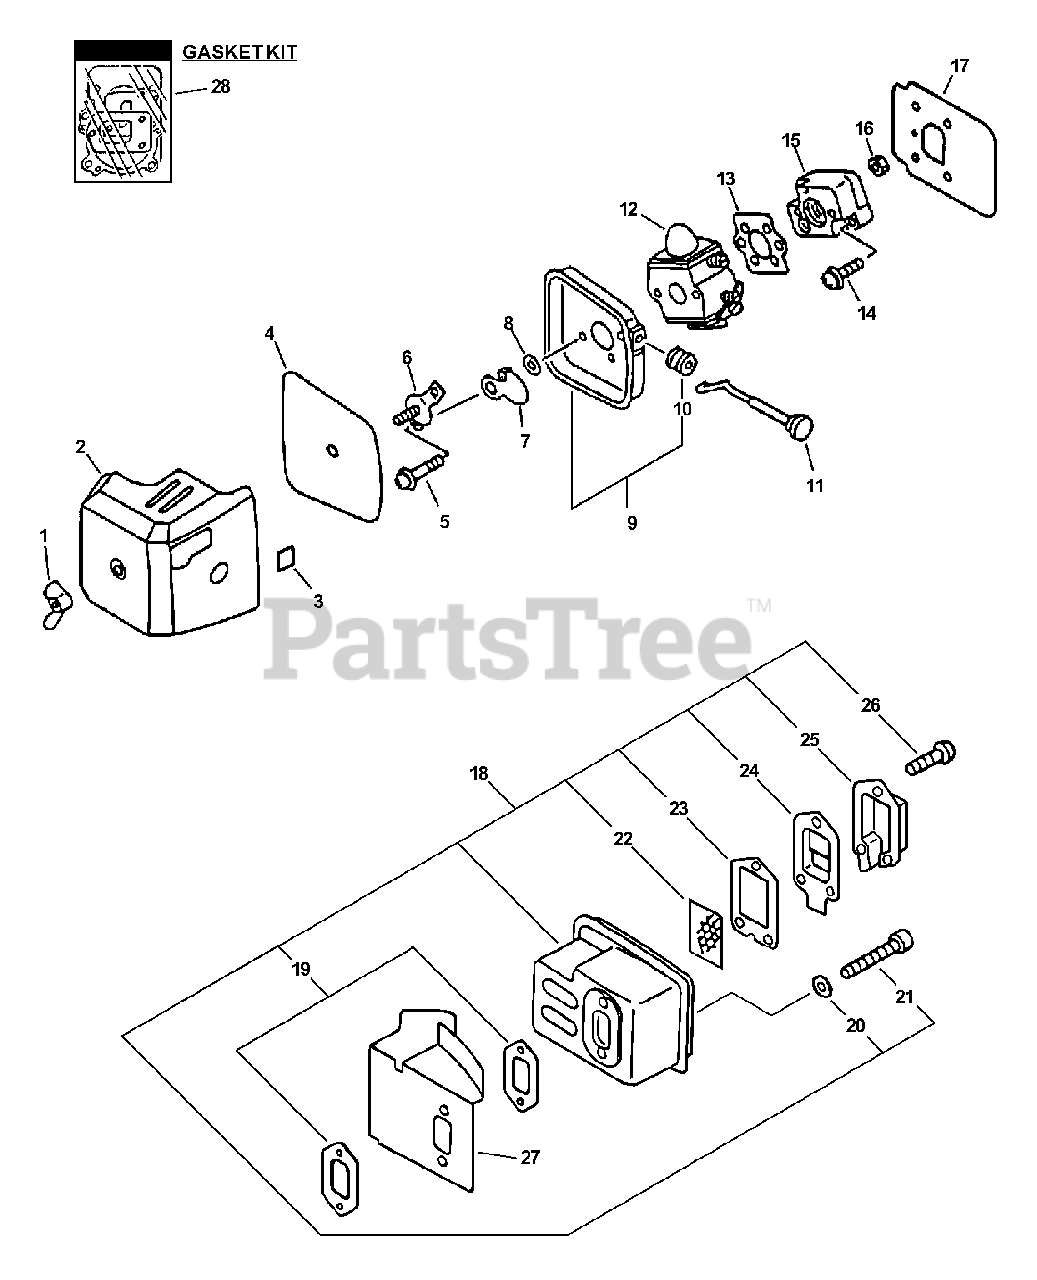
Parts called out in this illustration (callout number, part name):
1	WINGNUT - 6
2	COVER, AIR FILTER
3	LABEL - CHOKE
4	FILTER, AIR
5	SCREW - 5X57
6	PLATE, PREVENT
7	SHUTTER, CHOKE
8	WASHER - 5
9	CASE, AIR FILTER
11	ROD, CHOKE
12	CARBURETOR C1U-K54
12	CARBURETOR C1U-K54A
13	GASKET, INTAKE
14	SCREW - 5X20
15	INSULATOR, INTAKE
17	SHIELD, INTAKE
18	MUFFLER ASSY
19	GASKET, EXHAUST
20	WASHER - 5
21	SCREW - 5X50
22	SCREEN, SPARK ARRESTOR
23	GASKET, EXHAUST
24	GASKET, EXHAUST - INNER
25	GUIDE, EXHAUST - OUTER
26	SCREW - 4X10
27	SHIELD, EXHAUST
28	GASKET KIT
